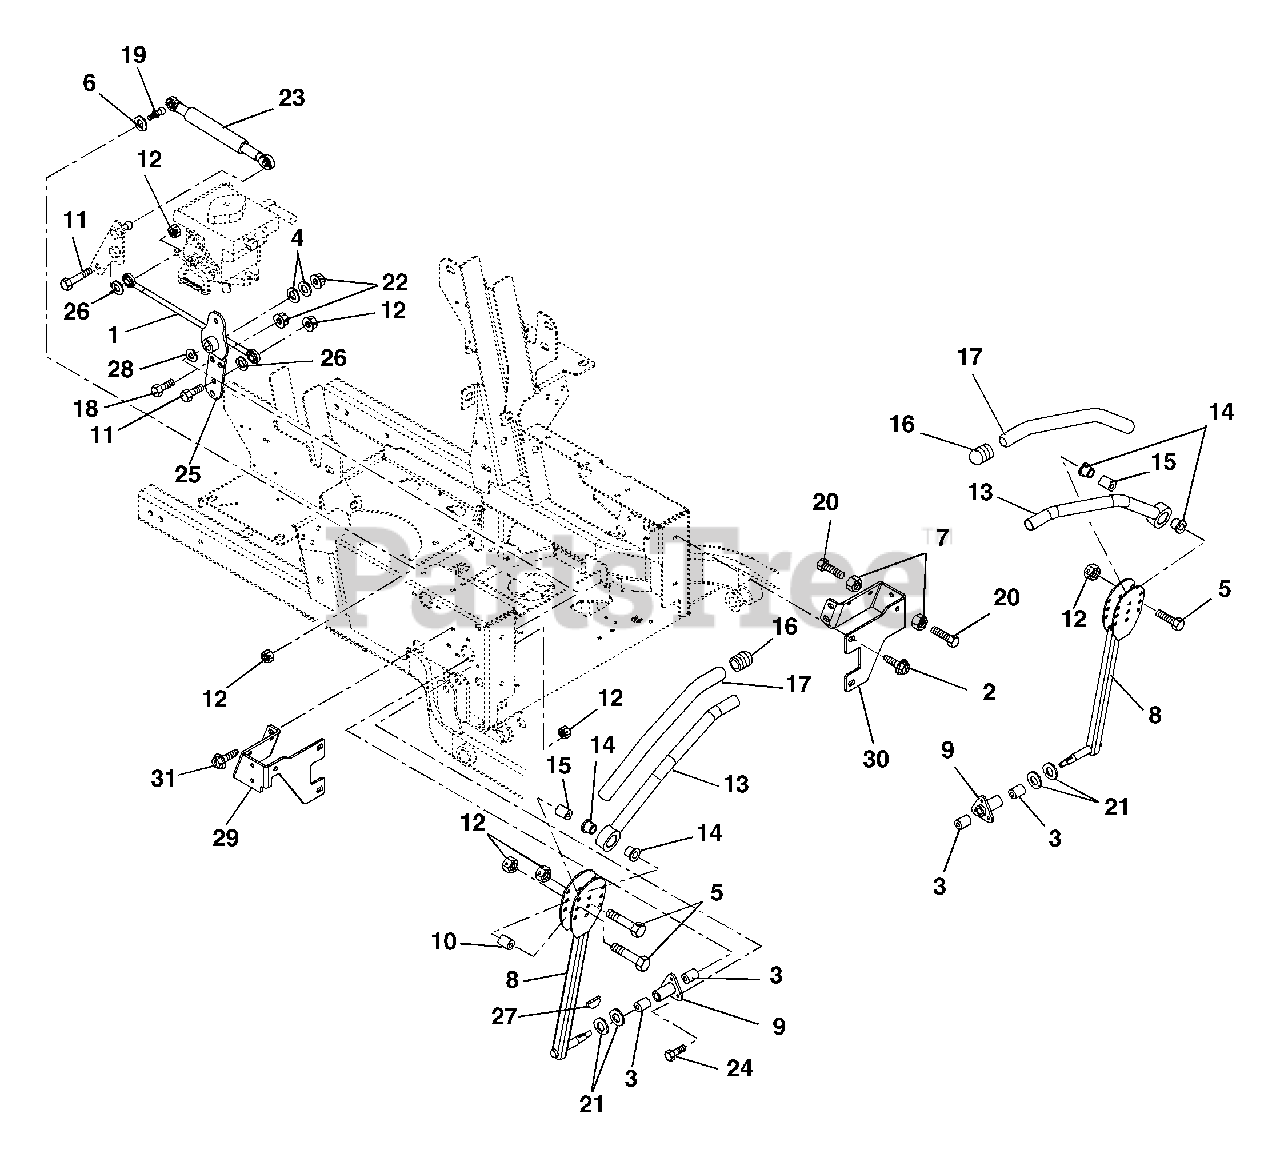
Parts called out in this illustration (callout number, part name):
1	Assembly, Steering Rod
2	Screw-Tapping .38-16 x .75 Hex Washer Head
3	Bushing .625 x .75 x .50
4	Washer-Flat-Steel .38 x .875 x .083
5	Bolt-Hex .31-18 x 1.75 Grade 5
6	Washer-Flat-Steel .344 x .688 x .065
7	Nut-Hex-Jam .375-16
8	Control Arm
9	Housing, Bushing
10	Eccentric
11	Bolt-Hex .31-18 x 1.25 Grade 5
12	Nut-Locking-Top-Flange .31-18
13	Handle Weldment Left-Hand
13	Handle Weldment Right-Hand
14	Bushing-Flange-Nylon .762 x 1.48 x .44
16	Caplug- Handlebar
17	Grip-Handlebar
18	Bolt-Hex .375-16 x 1.75
19	Stud, Ball
20	Bolt-Hex .38-16 x 1.25 Grade 5
21	Washer-Flat-Steel .63 x 1.005 x .062
22	Nut-Locking-Top-Flange .38-16
23	Dampener, Control
24	Bolt-Hex .31-18 x .75 Grade 5
25	Weldment, Pivot Arm
26	Washer-Locking .31 x .078 Regular
27	Key-Woodruff .13 x .63
28	Wave Washer
29	Stop, Steering-Right Hand
30	Stop, Steering-Left Hand
31	Screw-Tapping .38-16 x .50 Hex Washer Head
